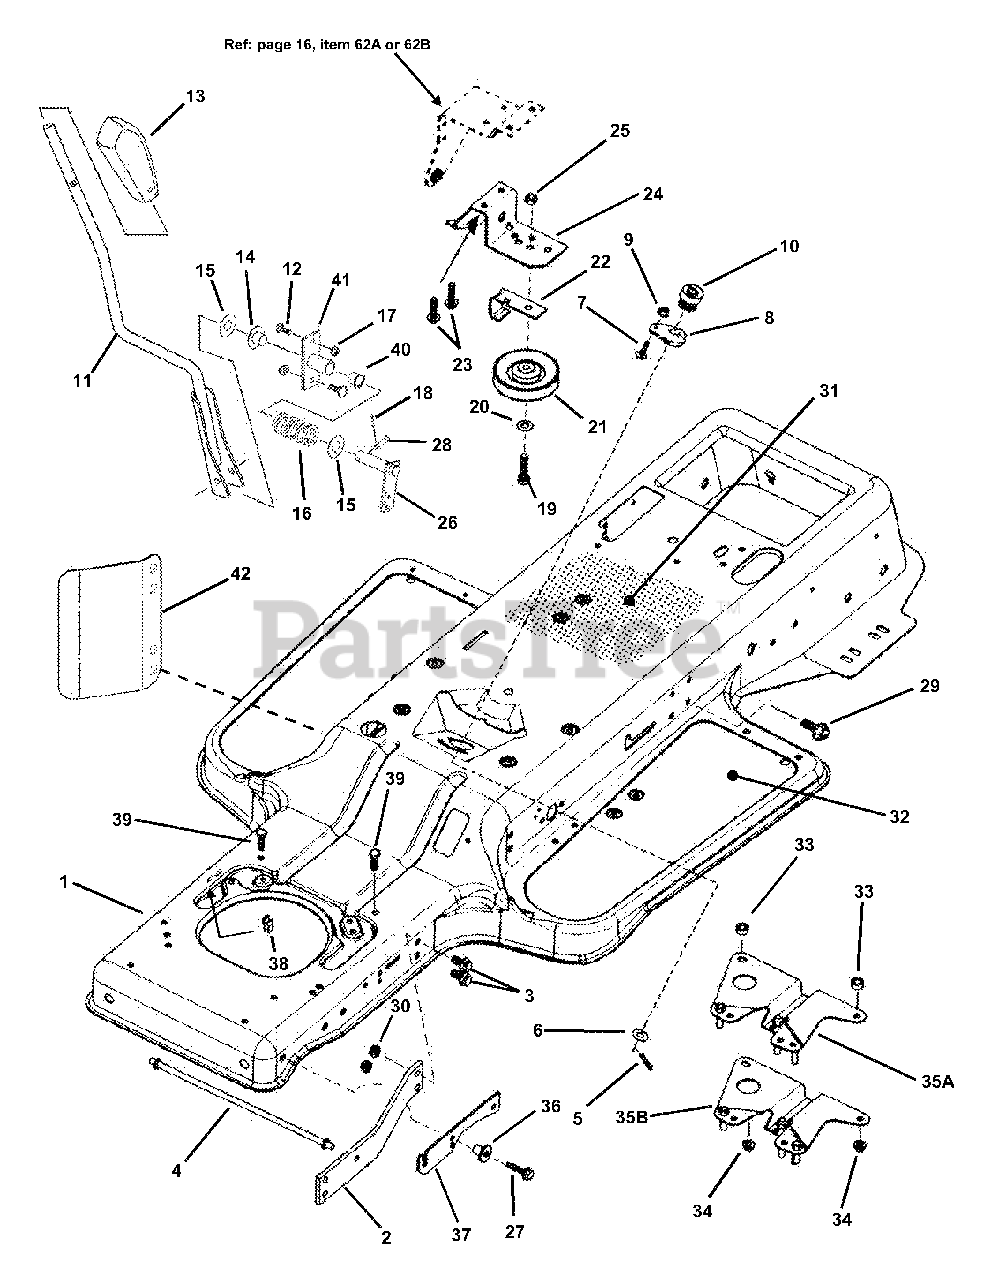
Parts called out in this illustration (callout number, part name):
1	FRAME, Tractor (1 Piece)
2	BRACE, Frame- 48"
3	BOLT, 3/8-16 x 3/4" Hex Flange Lock
4	GUIDE, Belt- 48"
5	COTTER-PIN, 1/8 x 3/4"
6	WASHER, 1/2 Shim
7	BOLT, 1/4-20 x 5/8" Short Neck Carriage, Grade 5
8	ASSEMBLY, Steering Adjuster
9	NUT, 1/4-20 Hex Flange Lock, Grade 5
10	GEAR, Steering Pinion
11	LEVER, Shift
12	BOLT, 5/16-18 x 3/4" Carriage
13	KNOB, Deck Lift Lever
14	BUSHING, 3/4 Flange
15	WASHER, Thrust
16	SPRING, Shift Detent
17	NUT, 5/16-18 Flange Lock
18	PIN, 3/32 x 3/4" Cotter
19	SCREW, 3/8-16 x 1-1/2" Hex Head Cap, Grade 5
20	WASHER, 3/8" Flat
21	PULLEY, Idler
22	GUIDE, Pulley Belt
23	SCREW, 5/16-18 x 1-1/4" Swage
24	SUPPORT, PTO Lever
25	NUT, 3/8-16 Hex Center Lock, Grade 5
26	STRUCTURE, Arm
27	SCREW, 5/16-18 x 1-1/4" Self-Tapping
28	PIN, 1/4 x 1-5/8" Clevis
29	SCREW, 5/16-18 x 5/8" Hex Washer Self-Tap
30	NUT, 3/8-16 Hex Flange Lock
31	DECAL, Instruction Frame Top (EC)
32	PAD, Foot (Rubber Deluxe)
33	SPACER, 11/32 x 5/8 x 5/16"
34	NUT, 5/16-18 Hex Flange Lock, Grade 5
35A	ASSEMBLY, Anti-Spin/Belt Guide
35B	ASSEMBLY, Anti-Spin/Belt Guide
36	BUSHING, Flange
37	BRACKET, Hood Pivot
38	CLIP, Wire
39	SCREW, 5/16-18 x 1" Hex Head Cap, Grade 2
40	BUSHING, 3/4 Flange
41	WELDMENT, Pivot Plate
42	SHIELD, Heat (Foot Rest)
